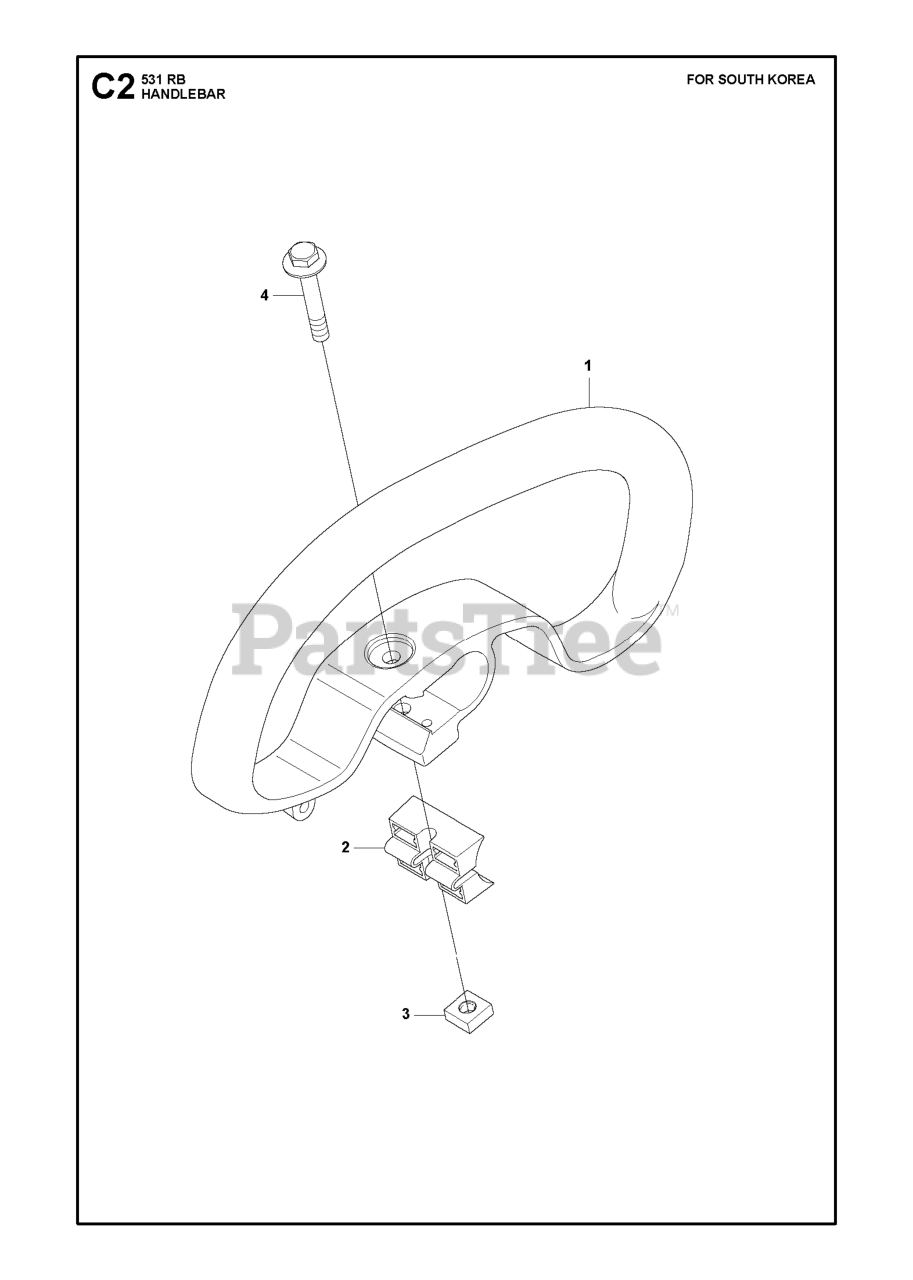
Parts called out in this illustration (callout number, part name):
1	HANDLE
2	SPACER PLASTIC
3	NUT
